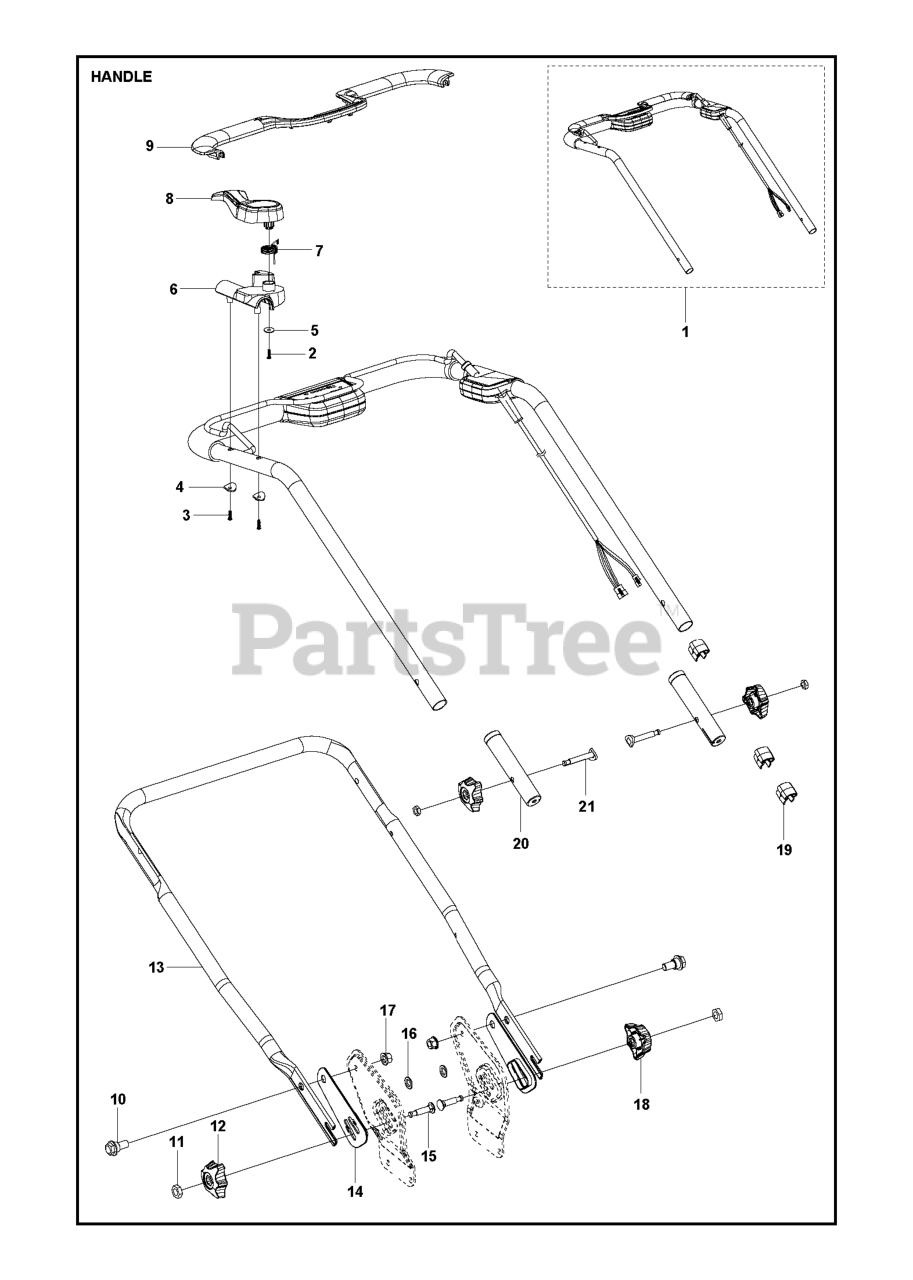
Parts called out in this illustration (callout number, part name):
1	HANDLE KIT DAYE# 90000305401
6	HOLDER BAIL STOP SOLUTION HOLD
7	TORSION SPRING
8	COVER BAIL STOP SOLUTION
9	COVER BAIL ARM COVER
11	HEXAGON NUT #26800502301
12	KNOB #25341500101
13	HANDLEBAR LOWER
14	PLATE RIGHT
16	SPACER RING
17	LOCKING BOLT M8,GB6187.1 #2680
18	PLATE LEFT
19	HOLDER CABLE
